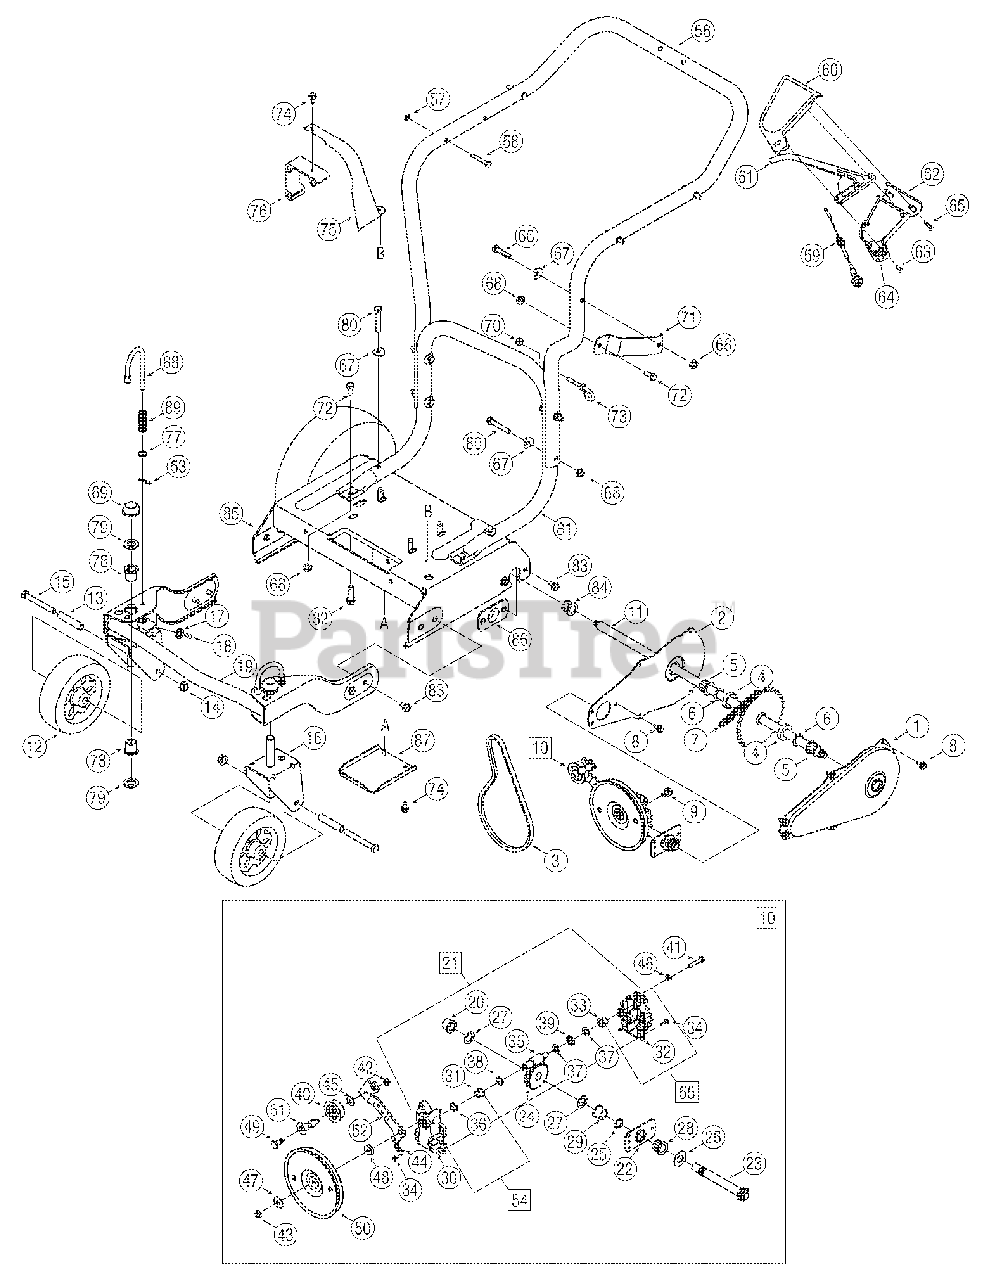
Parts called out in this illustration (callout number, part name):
3	V-Belt
5	Hex Flange Bearing
6	Flat Washer
7	Chain
8	TT Screw 1/4-14 x 0.625"
9	Hex Washer Screw 5/16
10	Chipper Shredder Trans.
11	Axle Assembly
12	Wheel 6.0 x 2.0
14	Flange Lock Nut 3/8-16
15	Hex Cap Screw 3/8-16 x
17	Flat Washer.203 ID x.403
18	Grease Fitting 3/16
20	Flange Bearing.566 ID
21	Shredder Transmission
23	Output Shaft 6T Sprocket
24	Helical 34T Gear
26	Flat Washer.64 ID x 1.24
27	Flat Washer 5/8 x 1.0
28	Hex Flange Bearing.631 ID
29	Flange Bearing.629 ID
30	Lower Housing
31	Flange Bearing.503 ID
32	Upper Housing
33	Flange Bearing.378 ID
34	Hex Washer Screw #10-16
35	Pinion Shaft 10T
36	Oil Seal
37	Thrust Washer.382 ID x.684
38	Flat Washer.504 ID x.70
39	Thrust Bearing.375 ID x.812
40	Idler Pulley Assembly W/
41	Hex Cap Screw 1/4-20 x
42	Hex Nut 1/4-28
43	Hex Jam Nut 5/16-24 LH
44	Extension Spring 1.12 Lg
45	Bell Washer.265 ID x.75 OD
46	Lock Washer 1/4
47	Bell Washer.325 ID x.930
48	Shoulder Spacer.375 ID x.165
49	Shoulder Bolt 1/4-28 x.375
50	Flat Pulley 5.06 Dia
51	Belt Keeper
52	Idler Bracket
53	Cotter Pin
54	Lower Housing Assembly
55	Upper Housing Assembly
58	Stud Pin.250 x 1.75
59	Clutch Cable 56"
60	Upper Clutch Cover
61	Drive Lever
62	Lower Clutch Cover
63	Screw #10-12 x.750
64	Mounting Cable Cap
65	Screw #10-16 x 1.25
66	Hex Cap Screw 5/16-18 x
67	Shoulder Washer.320 ID x.93
68	Hex Flange Lock Nut 5/16-
70	Hex Nut 1/4-28
72	Hex Cap Screw 5/16-18 x.
74	Hex Washer Screw 1/4-14
75	Belt Cover
76	Engine Mounting Adapter
77	Flat Washer.330 ID x.630
78	Flange Bearing.632 ID
79	Flat Washer 5/8 ID x 1.0
80	Hex Cap Screw 5/16-18 x
82	Screw 3/8-16 x 1.25
83	Hex Washer Screw 5/16-18
84	Hex Flange Bearing.631 x.720
89	Compression Spring
